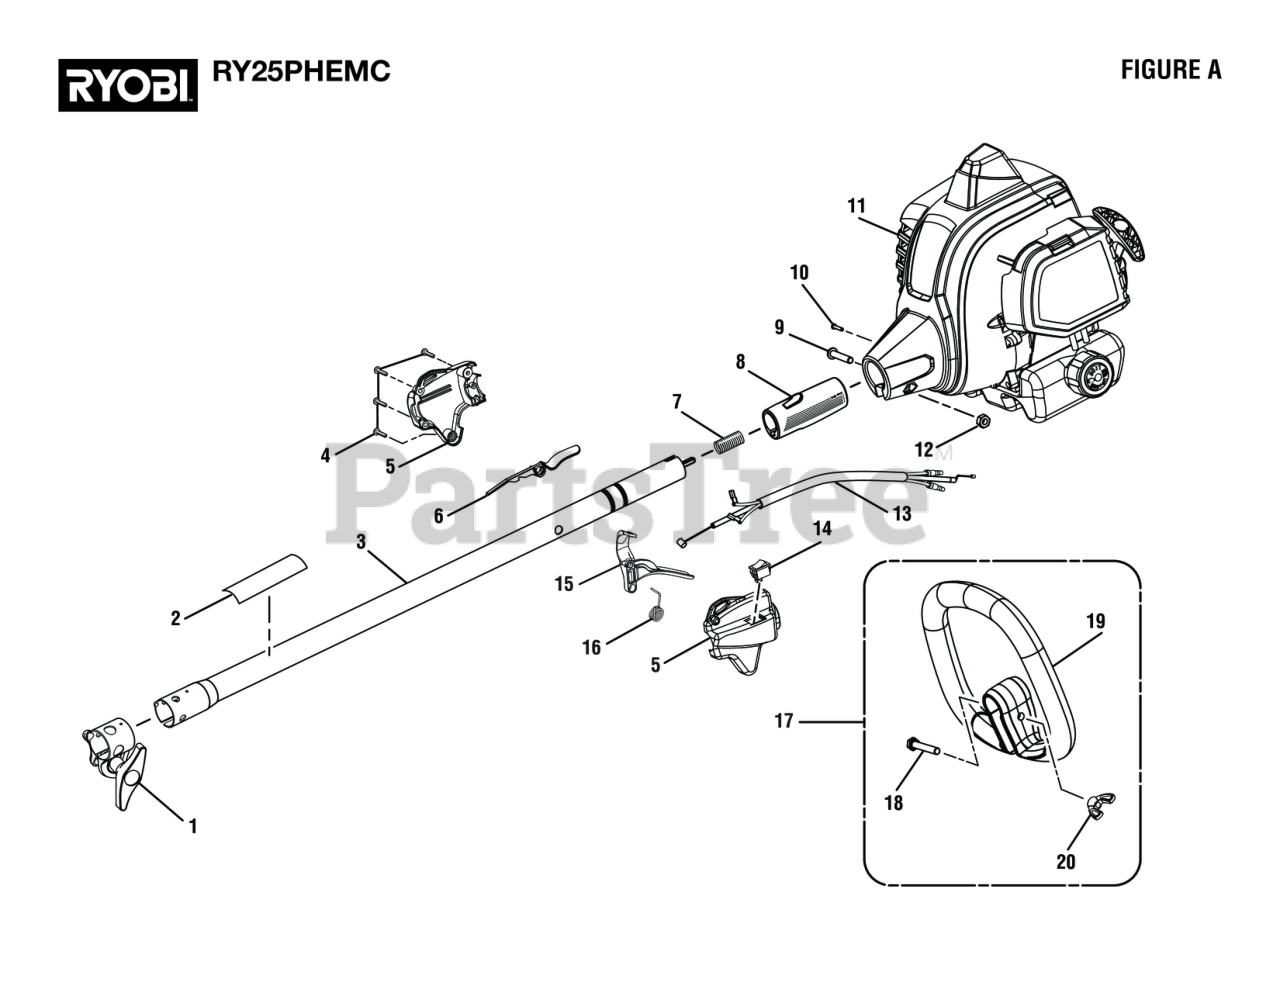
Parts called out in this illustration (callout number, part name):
1	Boom Clamp Assembly
2	Warning Icon Label
3	Upper Boom Assembly
4	Screw (M4 x 20 mm, T20 Torx Pan Hd. S.T.)
5	Control Handle Assembly (Inc. Key No. 6)
6	Trigger Lock
7	COMPRESSION SPRING
8	Rear Handle Grip
9	Screw (M6 x 30 mm, T27 Torx Button Hd.)
10	Screw (M4 x 8 mm, T25 Torx Pan Hd. T.F.)
11	Power Head Assembly
12	Hex Nut (M6.3 x 1)
13	Throttle Cable and Wire Assembly
14	Stop Switch (Momentary Contact)
16	Torsion Spring (Throttle Trigger)
17	Auxiliary Handle Assembly
18	Screw (1/4-20 x 40 mm, Cap Hex Hd.)
19	Front Handle
20	Wing Nut (1/4-20, Plastic)
